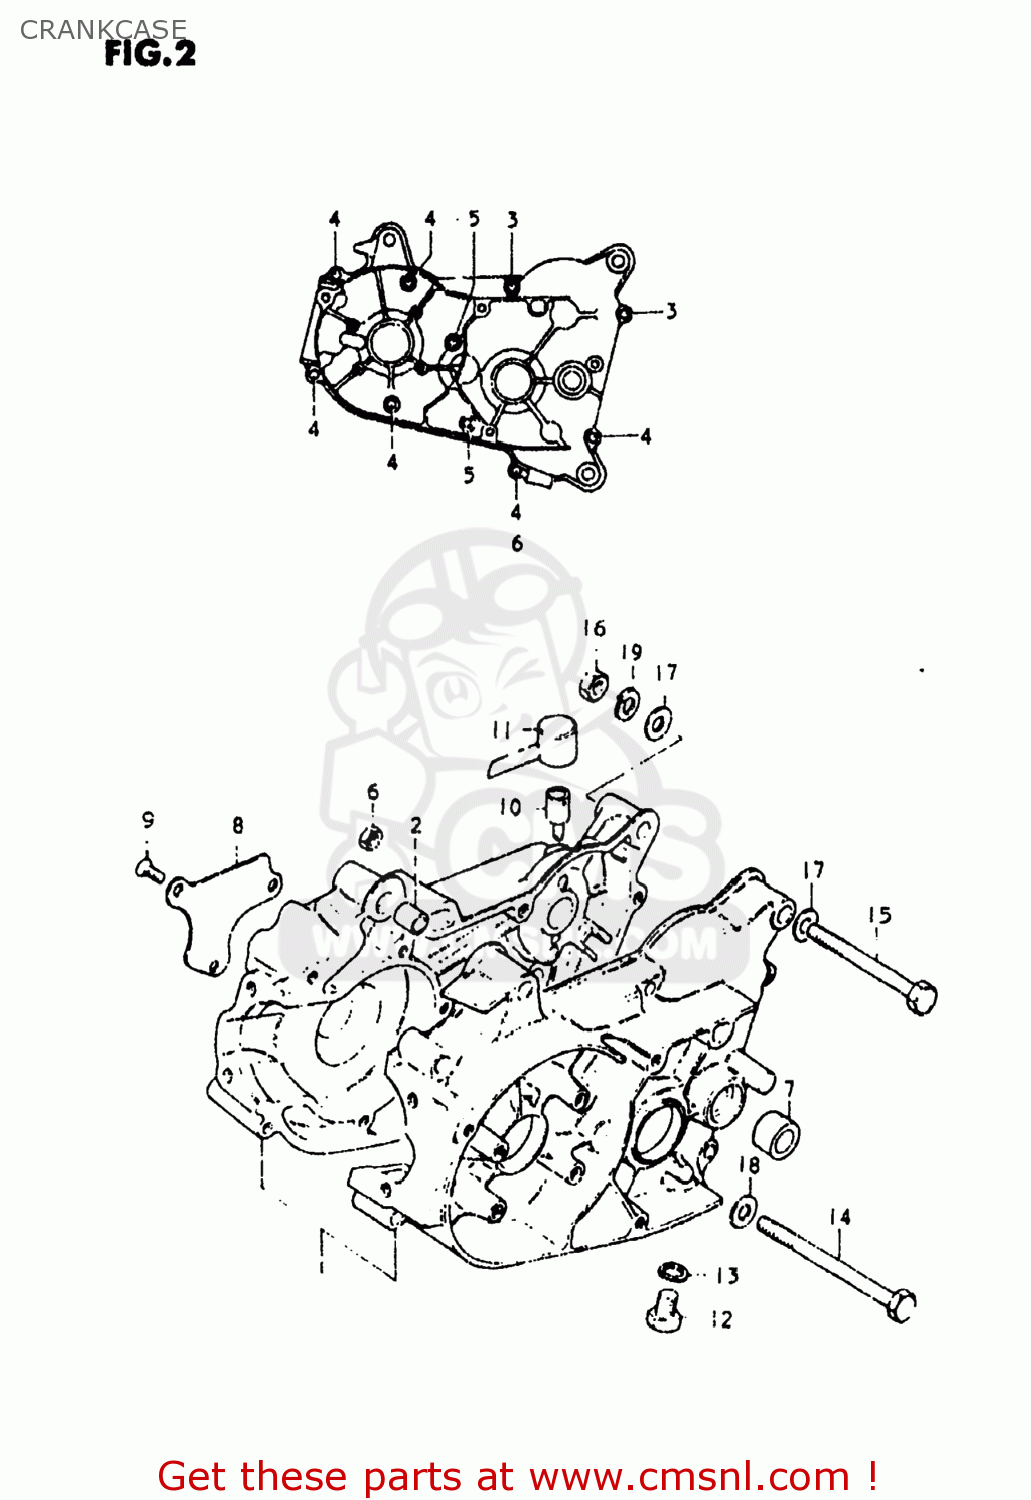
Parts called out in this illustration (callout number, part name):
1	CRANKCASE ASSEMBLY
2	PIN
3	SCREW 6X30
4	SCREW (6X35)
5	SCREW
6	NUT
7	BUSH
8	PLATE,OIL RESERVOIR
9	SCREW
10	PLUG,TRANSMISSION BREATHER
11	GASKET (NAS)
12	PLUG
13	GASKET(10X14X3.6) (NAS)
14	BOLT
15	BOLT
16	NUT
17	WASHER
18	WASHER
19	LOCK WASHER
